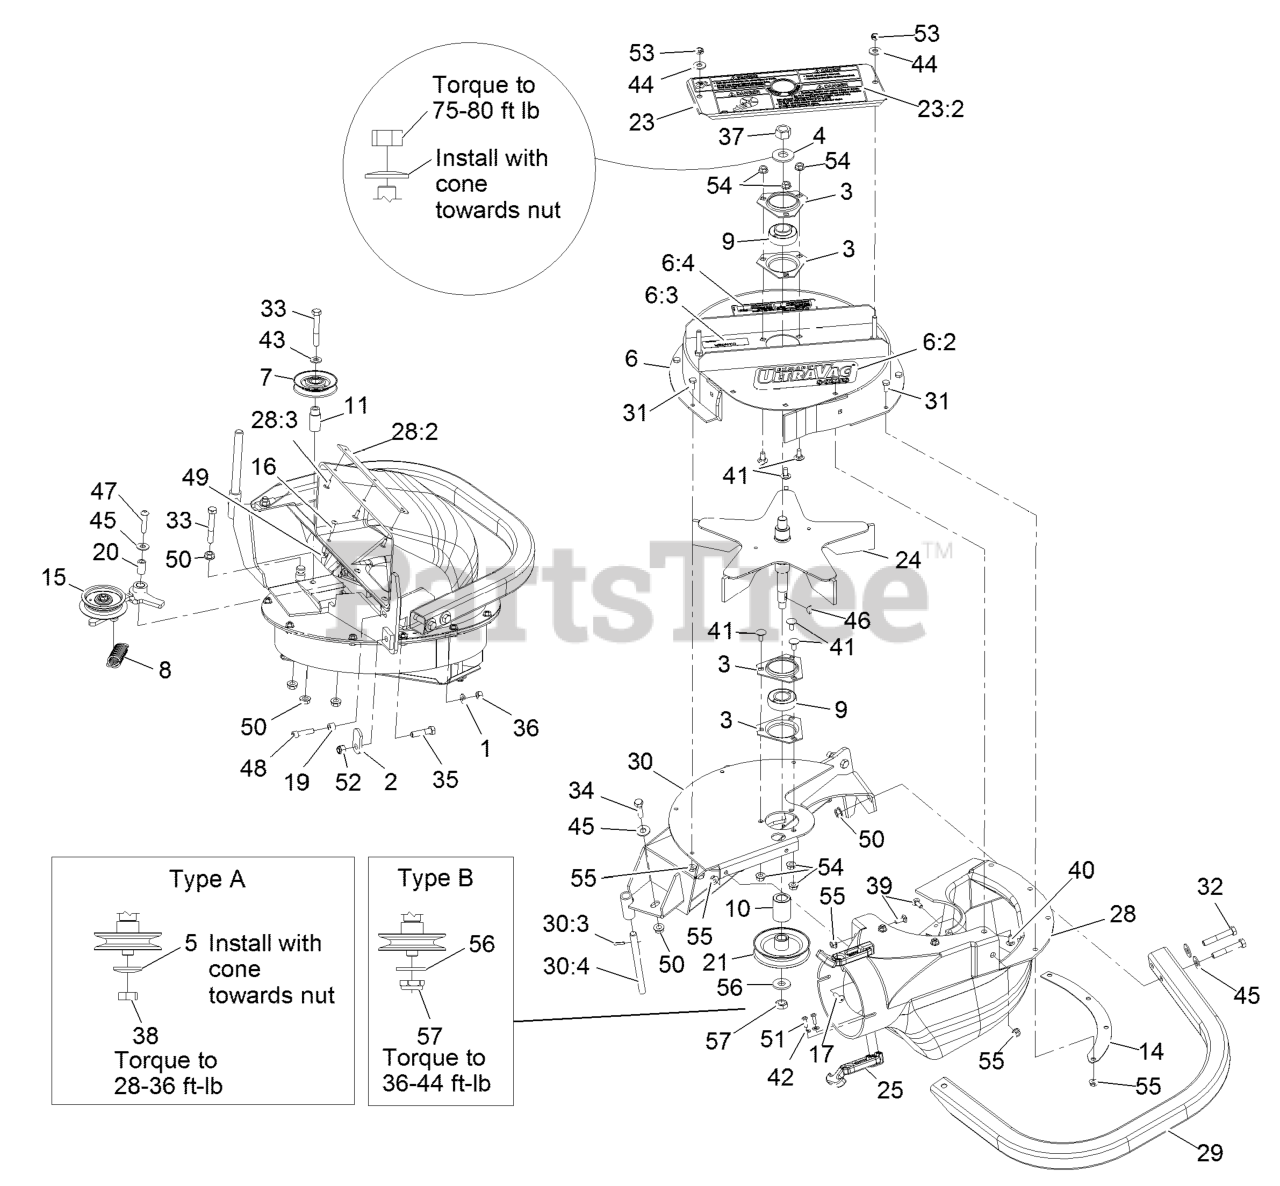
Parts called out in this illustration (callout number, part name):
1	WASHER-SPRING
2	LATCH-CATCHER, GRASS
3	HOUSING-FLANGE
4	WASHER-SPRING
5	WASHER-SPRING
6	ASM-UPPER HOUSING SMALL
6:2	DECAL-ULTRA VAC S-SERIES
6:3	DECAL-COVER, MISSING
6:4	DECAL,WEIGHT
7	IDLER-INSIDE
8	SPRING-IDLER
9	BEARING
14	PLATE-BACKING, BLOWER
15	Asm, Idler
16	SCREW-HEAD, TRUSS
19	BUSHING, LOCATOR
20	BUSHING-PIVOT, IDLER
21	SHEAVE-BLOWER
23	ASM, BEARING COVER
23:2	DECAL-WARNING
24	IMPELLER
25	LATCH-RUBBER
28	ASM,BLOWER CHUTE LHP
28:2	PLATE-REINFORCEMENT
28:3	RIVET-BLIND
30	WELD, FRAME SM BLOWER
30:3	PIN-ROLL
30:4	SHAFT-CATCHER, GRASS
31	SCREW-HH
32	SCREW-HH
33	BOLT-CARR
34	SCREW-HH
35	SCREW-HH
36	NUT-HEX
37	NUT-HEX
38	NUT-JAM
39	BOLT-CARR
40	SCREW-CARR
41	SCREW-CARR
42	WASHER-FLAT
43	WASHER-FLAT
44	WASHER-FLAT
45	WASHER-FLAT
46	KEY-WOODRUFF
47	SCREW-HSBH
48	SCREW-HSH
50	NUT-HHF, WHIZ
51	SCREW-PPH
52	NUT-LOCK, NI
53	NUT-LOCK, NI
56	WASHER-FLAT
57	NUT-LOCK, NI
